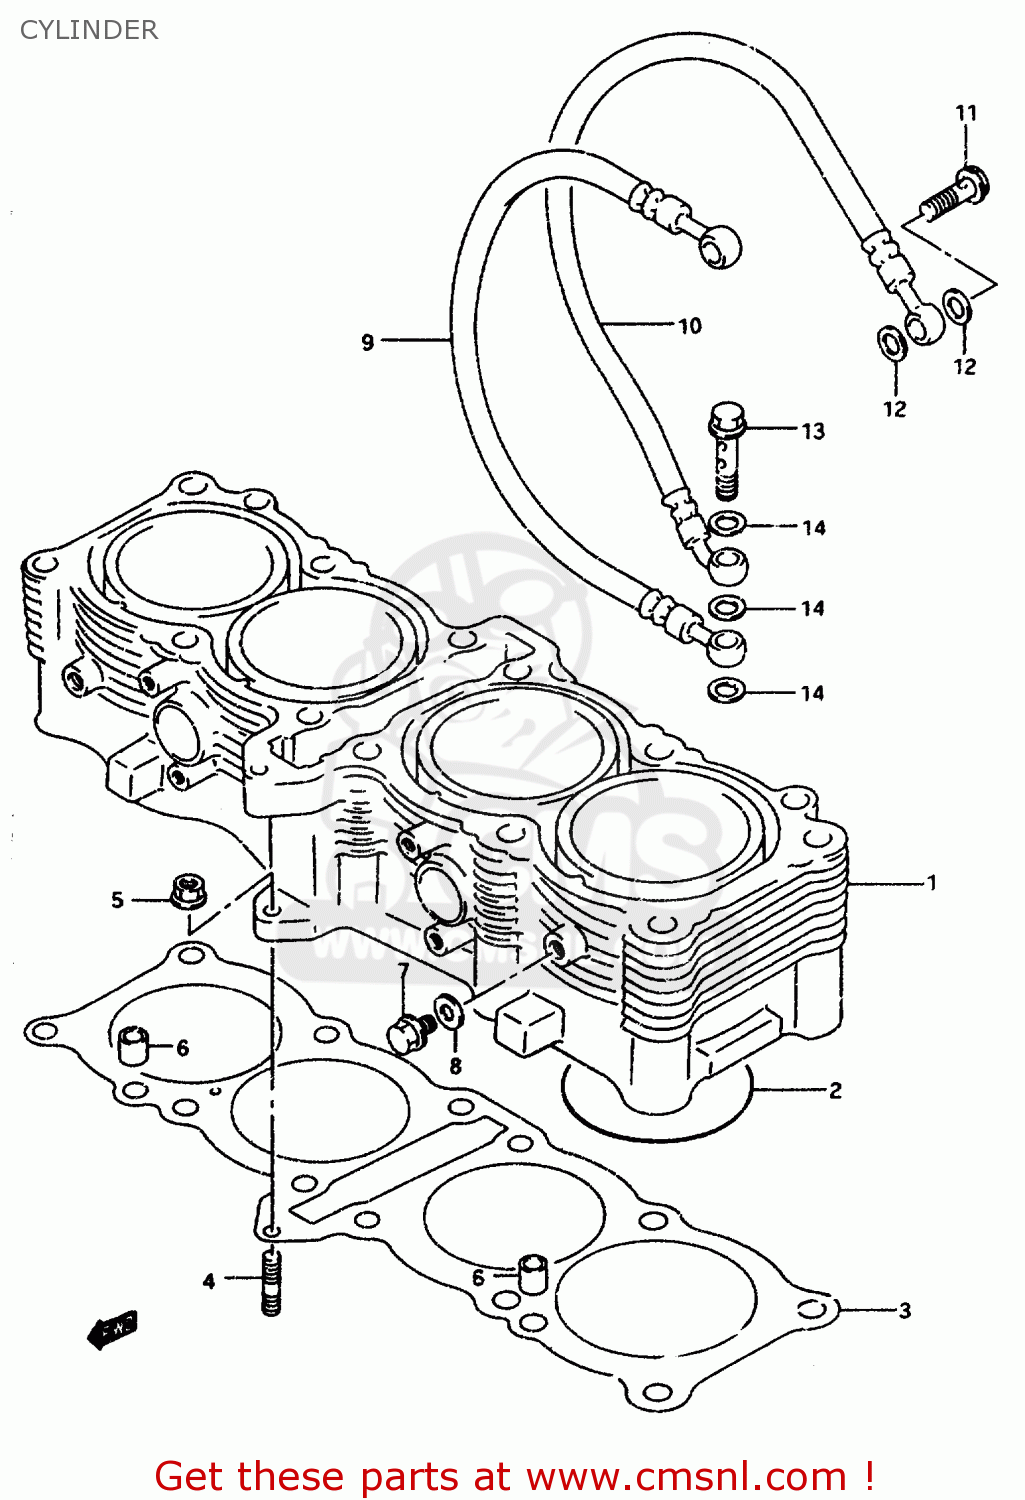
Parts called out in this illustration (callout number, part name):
1	CYLINDER
2	O RING(D:1.9,ID:79.5)
3	GASKET,CYLINDER
4	STUD,M6X1X32
5	NUT
6	PIN
7	BOLT,DRAIN
8	GASKET 8.2X14X1 (NAS)
9	HOSE,OIL
10	HOSE,OIL
11	BOLT,OIL PIPE UNION,NO
12	GASKET(8.2X14X1) (NAS)
13	BOLT,OIL PIPE UNION,NO
14	WASHER(10X15X1.5)
